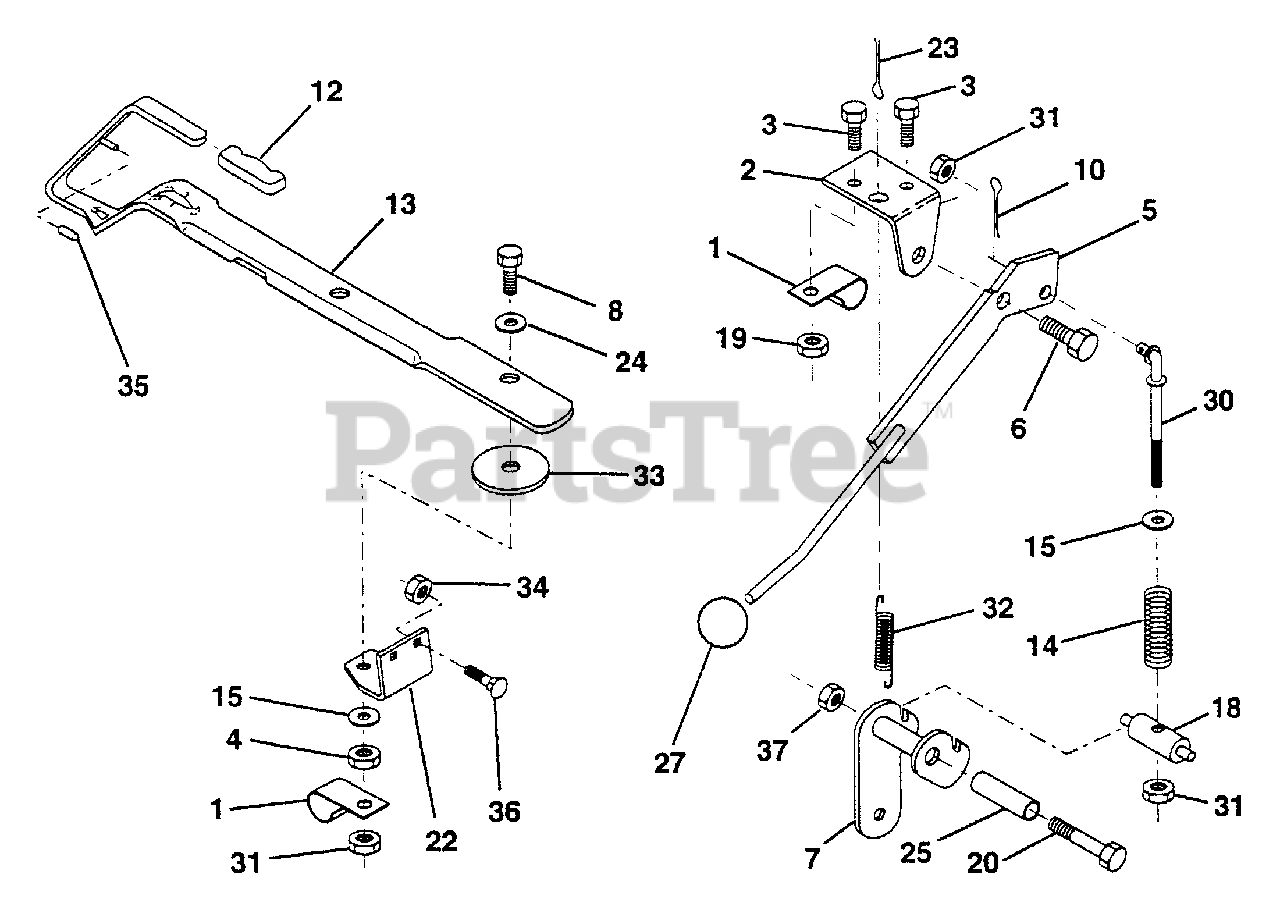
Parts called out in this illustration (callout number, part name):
1	Clip, Insulated
2	Bracket, Mower Clutch
3	Bolt, Hex Head, Fin. 1/4-20 UNC x 1/2 Grade 5
4	Nut, Lock Hex W/Ins. 3/8-16
5	Assembly, Clutch Lever
6	Bolt, Shoulder
7	Assembly, Mower Clutch Arm
8	Bolt, Hex Head 3/8-16 UNC x 1-1/2
10	Pin, Cotter 1/8 x 3/4
12	Handle, Lift Lever
13	Assembly, Lift Handle
14	Spring, Compression
15	Washer 13/32 x 1 x 11 Gauge
18	Trunnion, Threaded 3/8-16
19	Nut, Crownlock 1/4-20
20	Bolt, Hex Head, Fin. 3/8-16 UNC x 2-3/4
22	Bracket, Lift Lever
23	Pin, Cotter 3/32 x 3/4
24	Washer 25/64 x 1-1/4 x 12 Gauge
25	Tube, Spacer
30	Rod, Tension, Clutch
31	Nut Lock Hex w/wsh 3/8 - 16
32	Spring, Extension, Return
33	Washer .390 x 1.437 x .074
34	Nut, Lock Hx w/Ins 5/16-18
35	Cap, Vinyl, Red
36	Bolt, Carriage 5/16-18 x 3/4
37	Nut Crowniock 3/8-16
